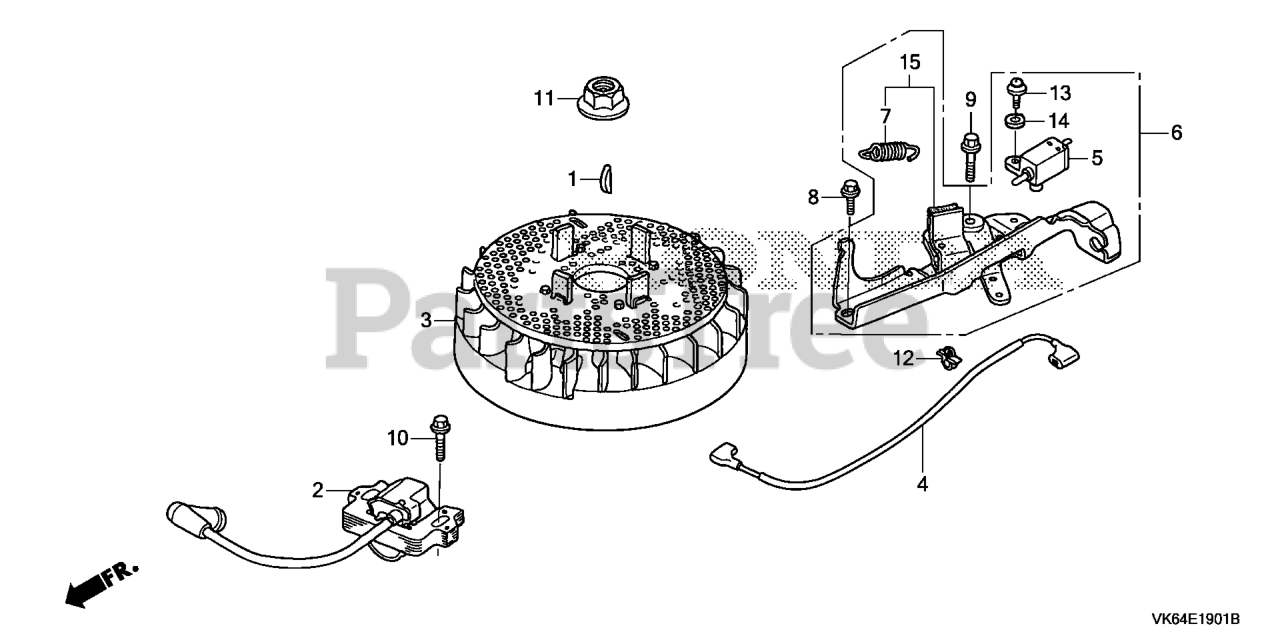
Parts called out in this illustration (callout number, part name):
1	KEY, SPECIAL WOODRUFF (25X18)
2	COIL ASSY., IGNITION (PHELON)
2	COIL ASSY., IGN
3	FLYWHEEL ASSY. (TEC) (USE FOR IGN. COIL OF TEC)
4	WIRE, STOP SWITCH
5	SWITCH ASSY., ENGINE STOP (Honda Code 5580683). (N.C)
6	BRAKE ASSY.
7	SPRING, BRAKE LEVER
8	BOLT, FLANGE (6X14)
9	BOLT, FLANGE (6X23)
10	BOLT, FLANGE (6X20) (CT200)
10	BOLT, FLANGE (6X23)
11	NUT, SPECIAL (14MM)
12	CLIP, CABLE (A)
13	SCREW-WASHER (4X12)
14	WASHER, PLAIN (4MM)
15	BRAKE ASSY.
